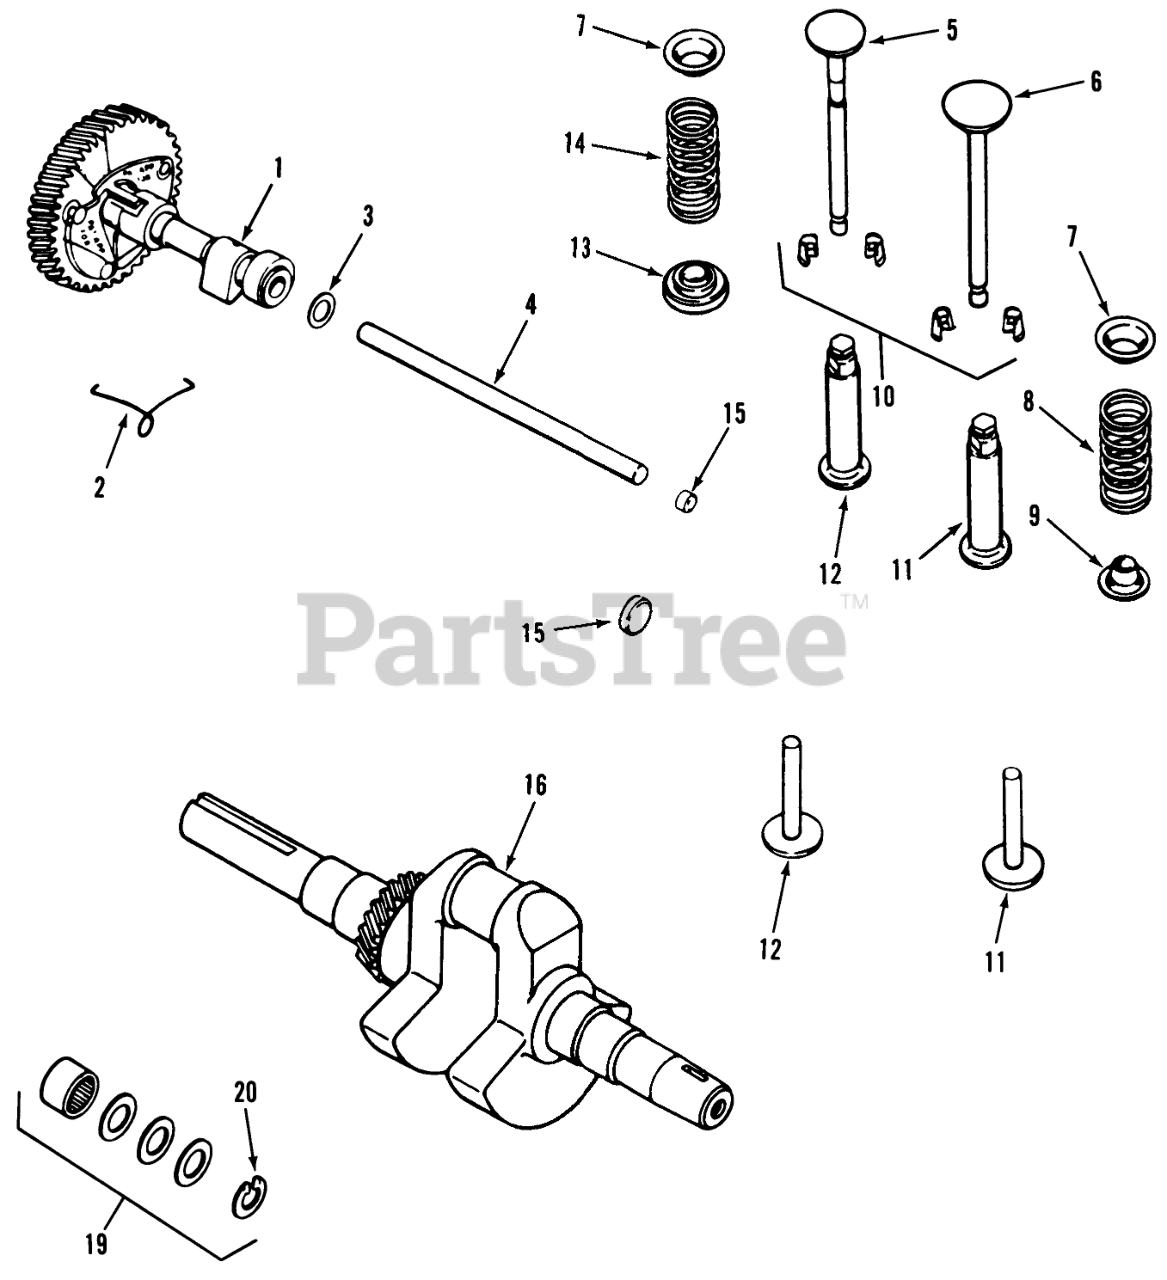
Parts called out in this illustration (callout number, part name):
1	Camshaft Assy (Includes Item 2)
2	Spring
3	Spacer .005
4	Camshaft Pin
5	Valve-Exhaust
6	Valve-Intake
7	UpperSpring Retainer
8	Spring
9	Retainer-Spring
10	Kit-Retainer
11	Tappet
12	Tappet
13	Rotator-Valve
14	Spring
16	Crankshaft Kit 3-25/32 x 1-1/8 (Includes Flywheel Hdwr.) 310
19	Spacer Kit (Includes Item 20) 312
20	Retainer
